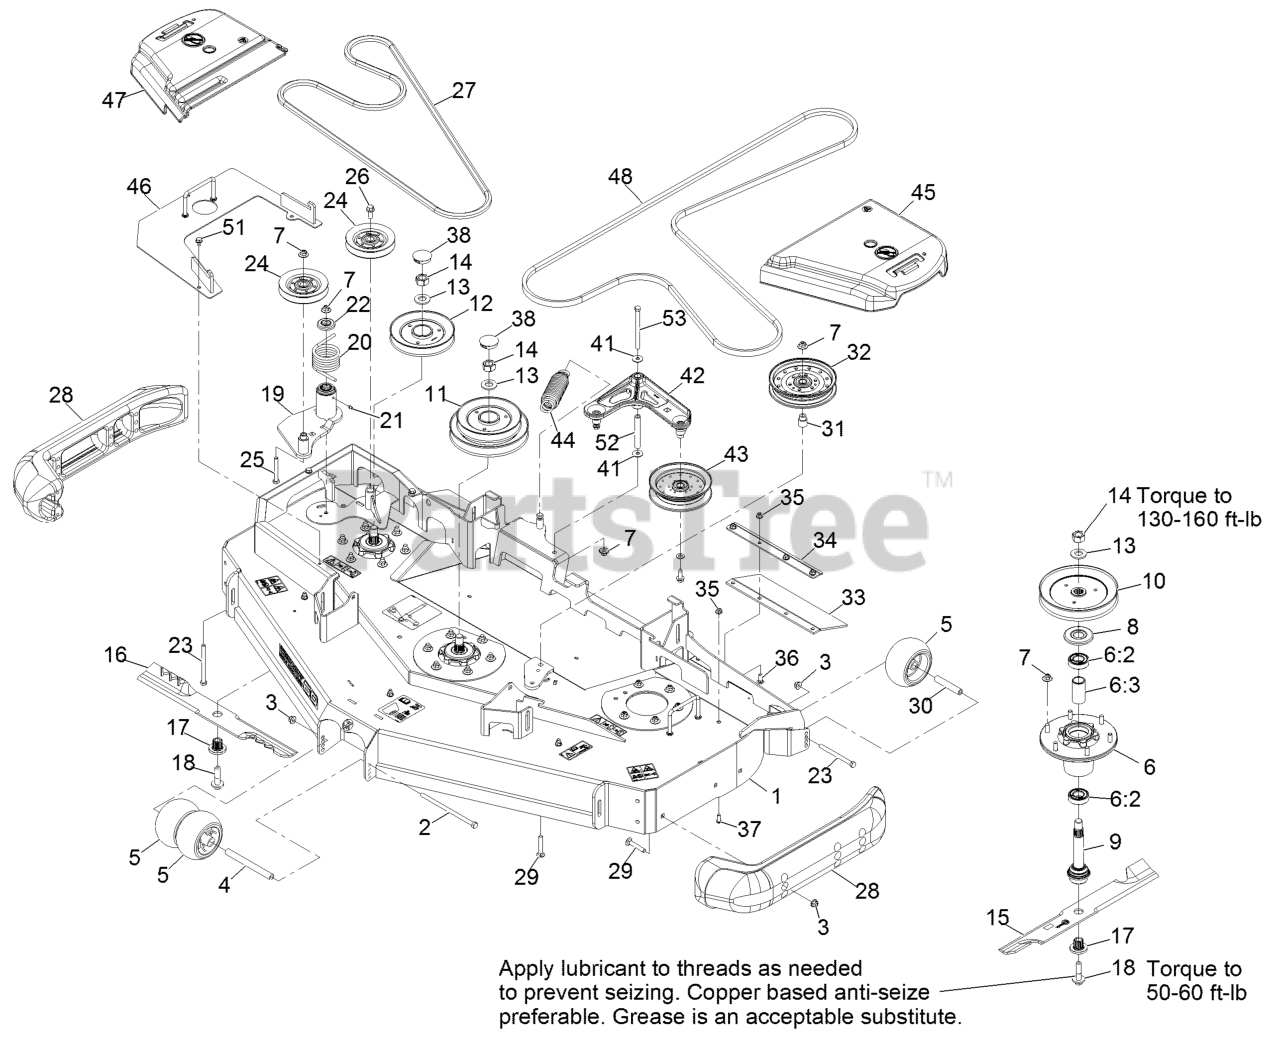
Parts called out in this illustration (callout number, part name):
1	DECK-PIONEER 60RD,W/DECAL
2	SCREW-HH
3	NUT-HF, NI
4	SPACER-WHEEL
5	ROLLER-SCALP, ANTI
6	ASM-CUTTER HSG WITH BEARINGS
6:2	BEARING-BALL
6:3	SPACER-BEARING
7	Nut-Nyloc 3/8-16 Flg
8	GUARD,BEARING TOP .989
9	ASM-SPINDLE AND SEAL
10	SHEAVE,BLADE DRIVE 7.25
11	SHEAVE, DOUBLE 60RD
12	SHEAVE-RD REV DRIVE SERIE
14	NUT-HEX
15	Blade-Extreme 2, 20.50"
16	Blade-Extreme 2-20.50, Rd60
16	Blade-Low Lift 20.5, Rd60
17	BUSHING,SPLINED
18	SCREW,SEMS 1/2-20 X 2.19
19	IDLER ASM
20	SPRING-TORSION
21	FITTING-GREASE
22	GUARD-TOP
23	SCREW-HH
25	SCREW-HH
26	SCREW-HHF
27	BELT
28	SKID-BUMPER, DECK
29	Bolt-Carriage 3/8-16 X 2 1/4
30	TUBE-SPANNER
31	BUSHING-IDLER
33	GUARD-TIRE
34	SUPPORT-OUTER FLAP
35	NUT-HF, NI
36	SCREW-CARR
37	SCREW-HSBH
38	PLUG,BLACK NYLON 1.75
42	IDLER ARM ASM
44	SPRING-EXTENSION
45	COVER-BELT, LH
46	Cover-Reverse Drive,Pioneer 60Rd
47	COVER-BELT, RH
48	BELT - V, B
52	BUSHING
53	SCREW-HH
